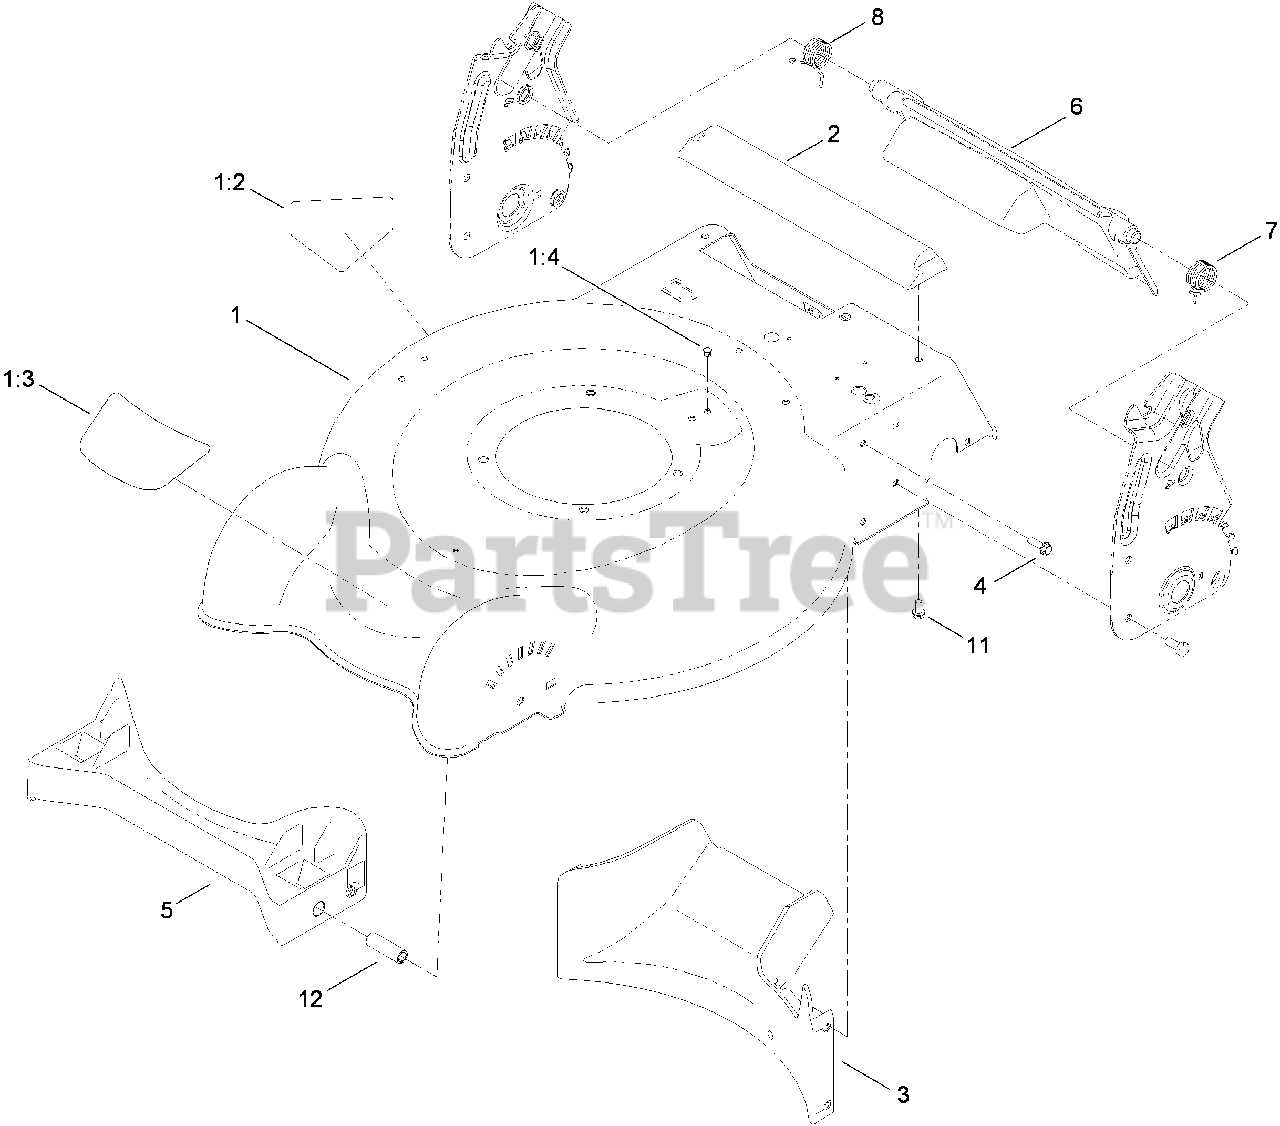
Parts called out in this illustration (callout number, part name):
1	HOUSING ASM
1:2	DECAL-DANGER
1:4	Plug-Dome
2	CHUTE-REAR
3	BAFFLE-REAR
4	SCREW-HWH
5	BAFFLE-FRONT
6	Rear Deflector ASM
7	SPRING-TORSION, LH
8	SPRING-TORSION, RH
11	SCREW-PLASTITE
12	SPACER-BAFFLE, FRONT
